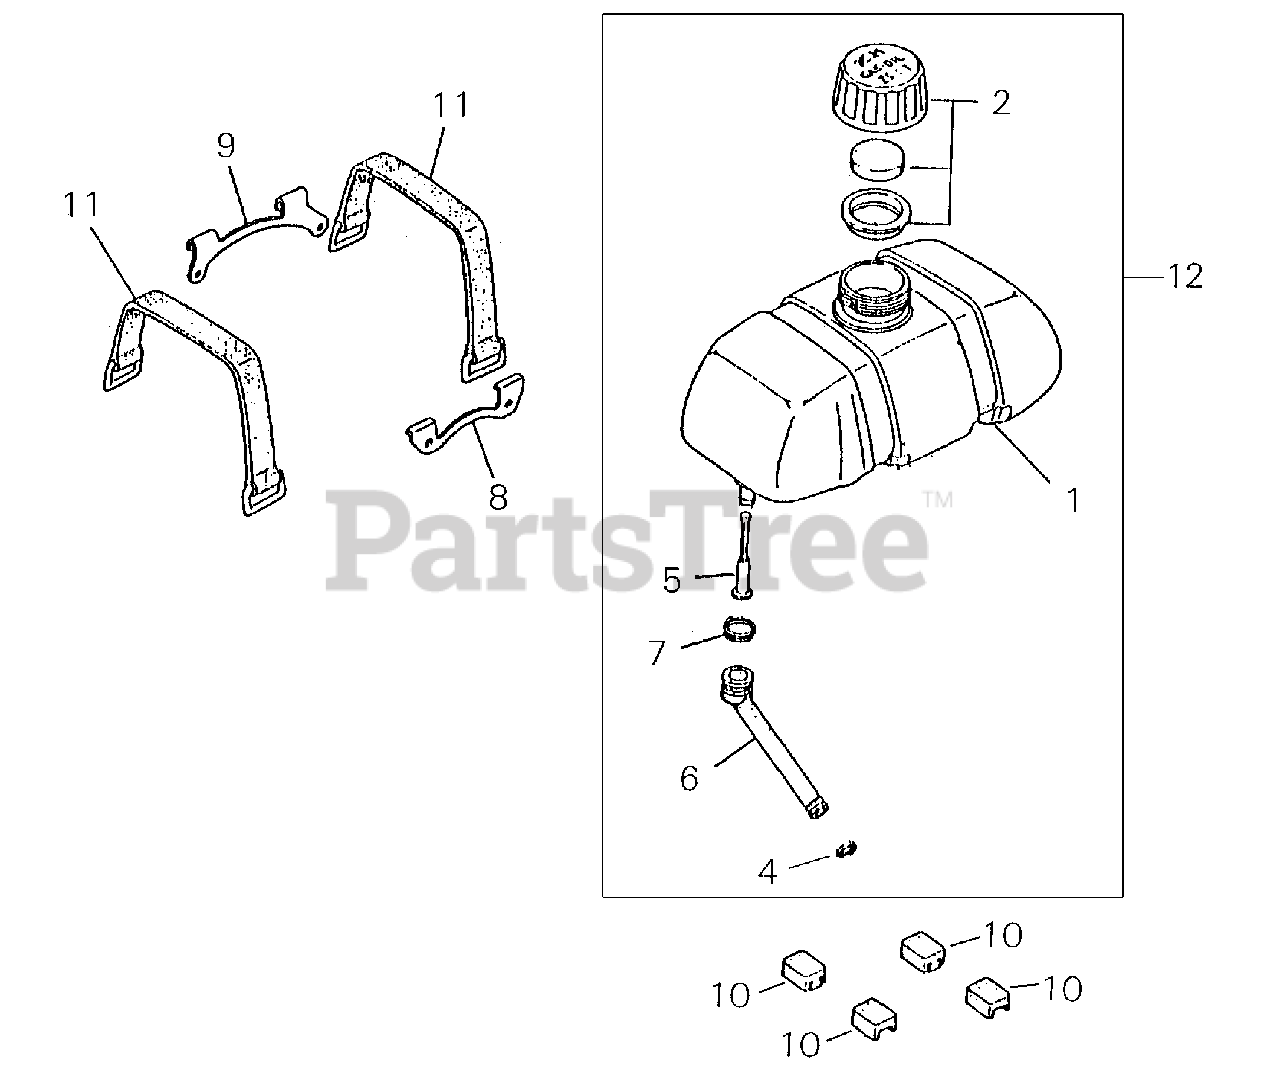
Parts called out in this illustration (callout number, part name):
1	TANK, FUEL
2	CAP ASSY
4	CLIP
5	FILTER, FUEL
6	PIPE - FUEL
7	CLAMP
8	BRACKET - OUTER
9	BRACKET - INNER
10	CUSHION
11	STRAP
12	FUEL TANK ASSY
